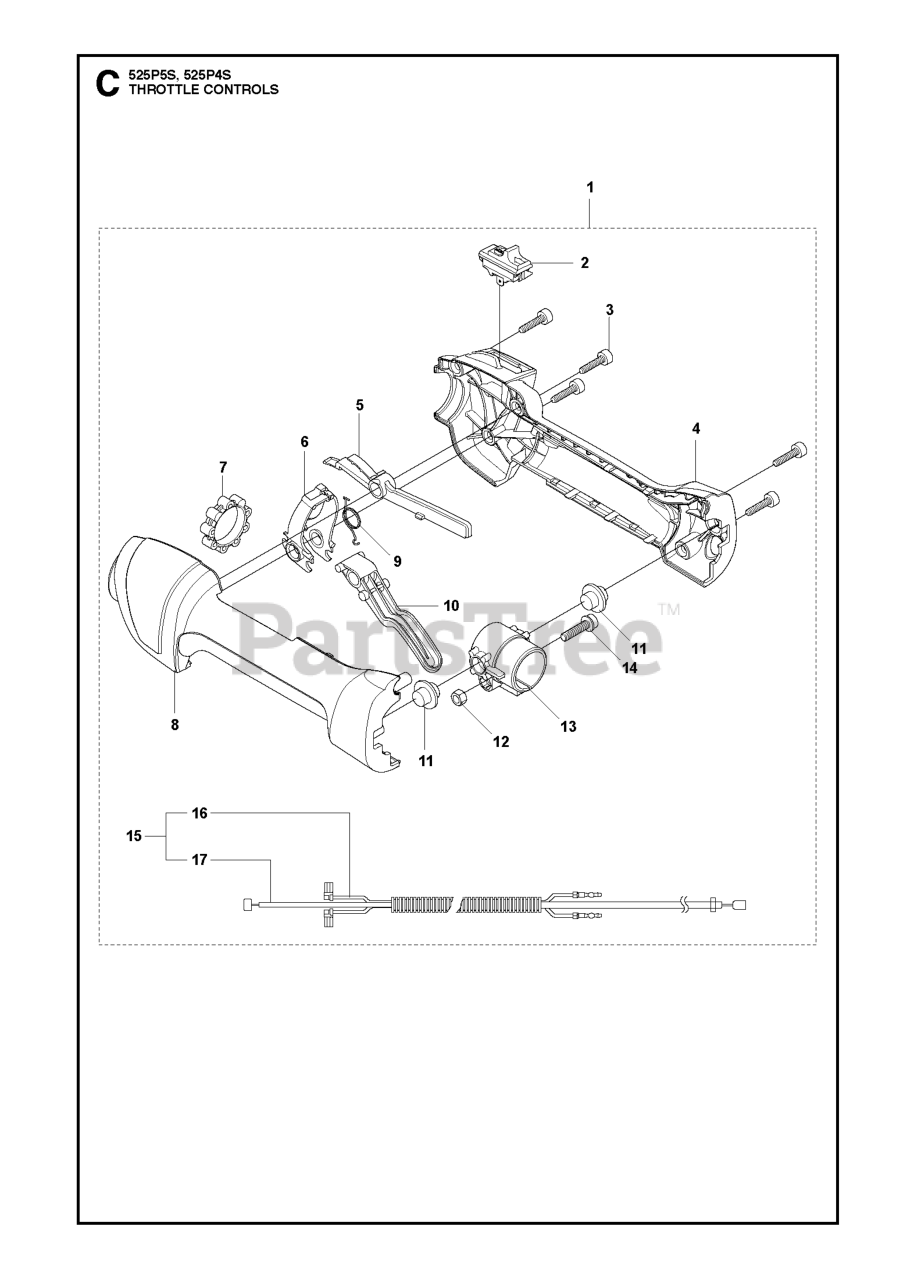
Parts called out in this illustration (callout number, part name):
1	THROTTLE CONTROL
1	THROTTLE CONTROL ASSY
2	STOP BUTTON
3	SCREW
4	HANDLE
5	THROTTLE LOCK
6	LEVER
7	VIBRATION DAMPER
8	HANDLE
9	RETURN SPRING
10	THROTTLE TRIGGER
11	VIBRATION ABSORBER
12	NUT
13	HOLDER
14	BOLT TORX
15	WIRING ASSY
16	SHORT CIRCUIT CABLE
17	THROTTLE CABLE
